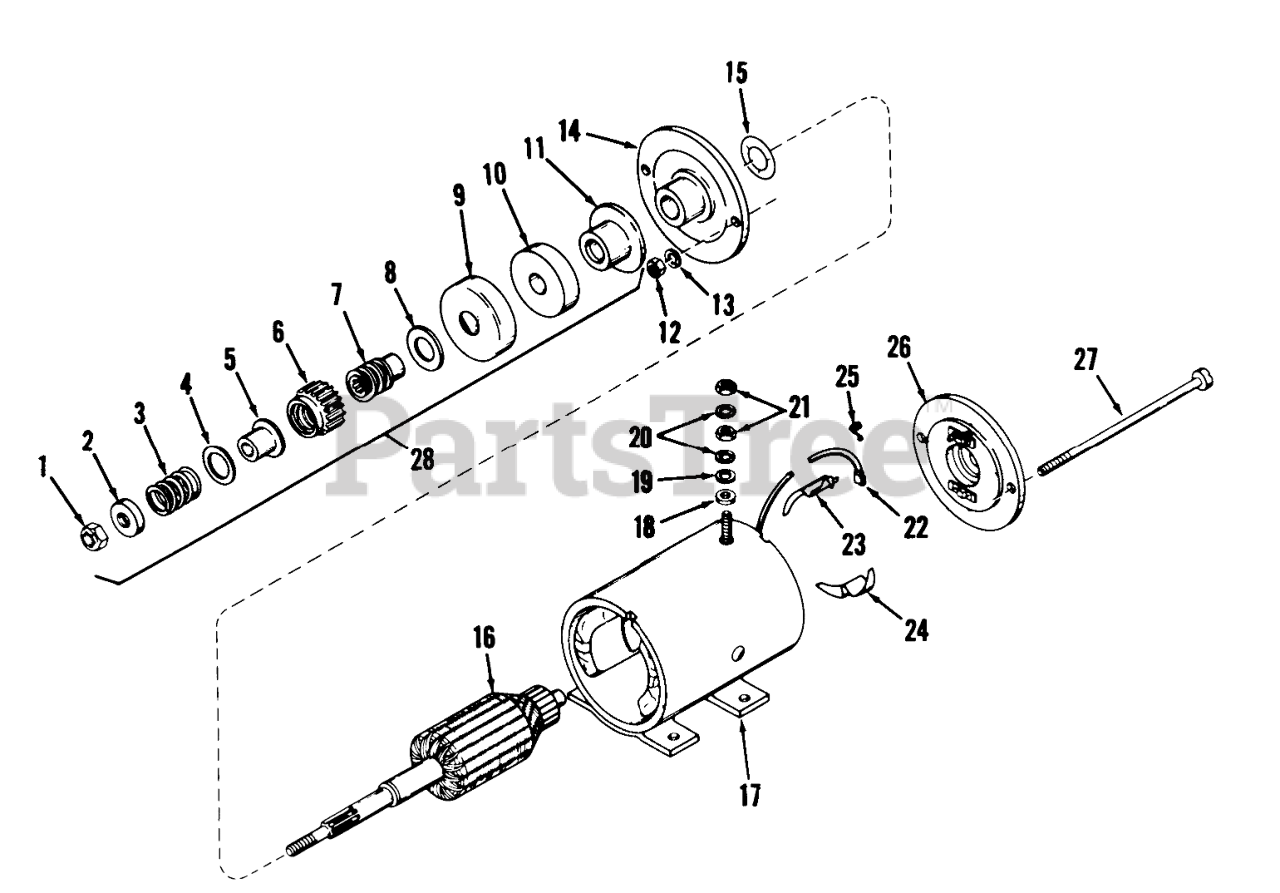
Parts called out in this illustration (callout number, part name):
1	Nut, Elastic stop
2	51084 3 1/2HP W/334
3	Spring, Anti-drift
4	Washer, Pinion
5	Sleeve, Anti-drift
6	Gear, Pinion
7	Shaft, Screw
8	Washer, Thrust
9	Cup, Cushion
10	Cushion, Rubber
11	Washer, Thrust
12	Nut, Securing
13	Washer, Lock
14	Cap Assy., Drive End (Incl. Bearing)
15	Washer, Spacing (.010 thick)(Use as required)
15	Washer, Spacing (.02 thick)(Use as required)
16	Armature
17	Housing Assy. (Incl. pole shoes, field coils, terminal post, straight mounting bracket, Nos. 18 thru 21, 23, 24, & 1 of 22).
18	Washer, Insulating
19	Washer, Plain
20	Washer, Lock
21	61710/VAR.HILLER AT
22	Brush & Spring Kit (Incl. No. 25)
23	Insulation
24	Insulation
25	Spring, Brush
26	End Cap Assy., Commutator (Incl. Nos. 25 & 1 of No. 22)
27	Bolt, Thru
28	Drive Assy., Complete (Incl. Nos. 1 thru 11)
